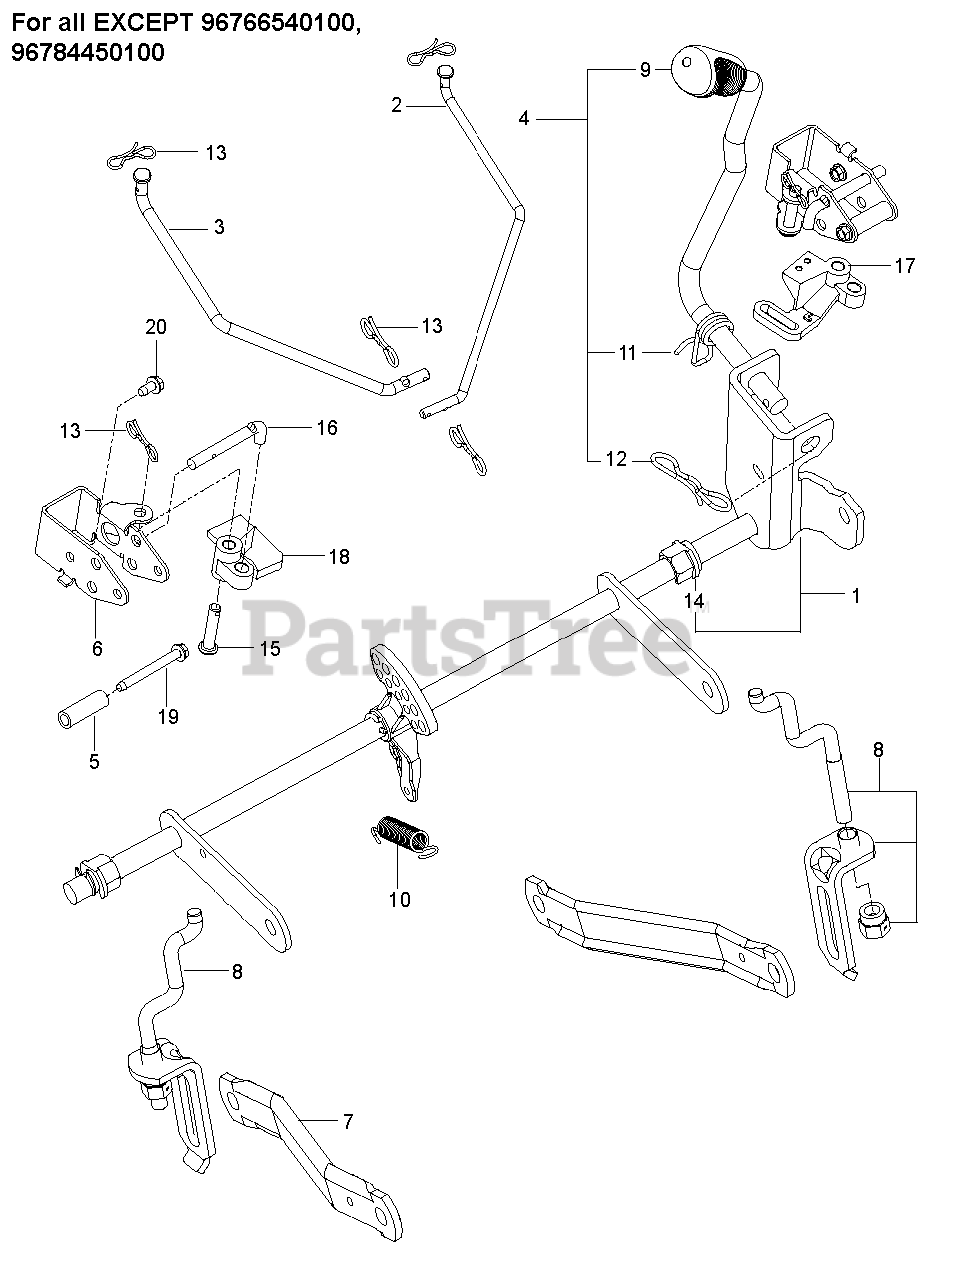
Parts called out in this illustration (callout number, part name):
1	SHAFT.ASM.RZ.DECK.LIFT.SRV
2	LINK.BRAKE.PARK.UPPER.LH
3	LINK.BRAKE.PARK.UPPER.RH
4	LIFT.LEVER.ASM.RZ.SERVICE
5	SPACER.334.ID.5.OD.1.5.L
6	BELLCRANK.BRACKET
7	ARM.SUSPENSION.MOWER
8	LINK.ASM.RZ.LIFT.SERVICE
9	GRIP.HANDLE.LIFT.PVC.428
10	RETURN.BRAKE.PARK.AUTO
11	SPRING.TORSION.LIFT.HANDLE
12	PIN.COTTER.7/16.BOW TI.
13	PIN COTTER;LOCKING;BOWTIE;1IN
14	PLASTIC NUT
15	PIN.5.16X1.5
16	ROD.PUSH.BRAKE
17	BELLCRANK.LH
18	BELLCRANK.RH
19	SCREW THD;ROLL;1/4-20 X 2.25
20	SCREW.1/4-20X5/8
